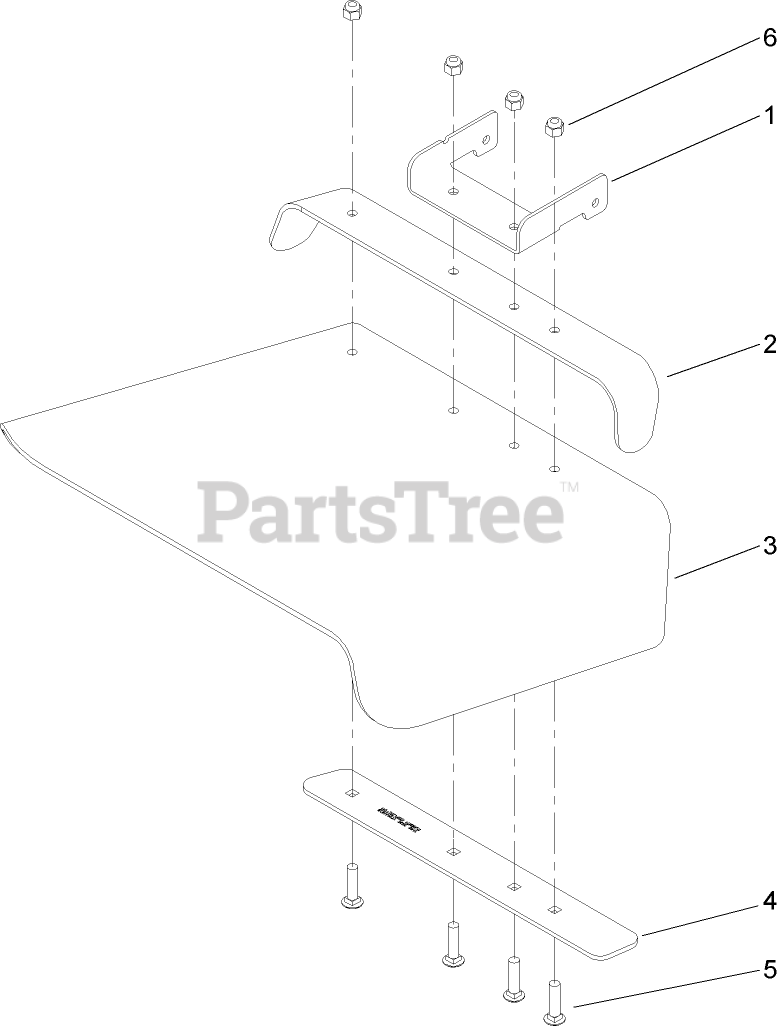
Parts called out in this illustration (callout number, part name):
1	HINGE-DEFLECTOR
2	SUPPORT-DISCHARGE
3	DEFLECTOR-RUBBER
4	STRAP-DISCHARGE
5	SCREW-CARR
6	NUT-LOCK, NI
